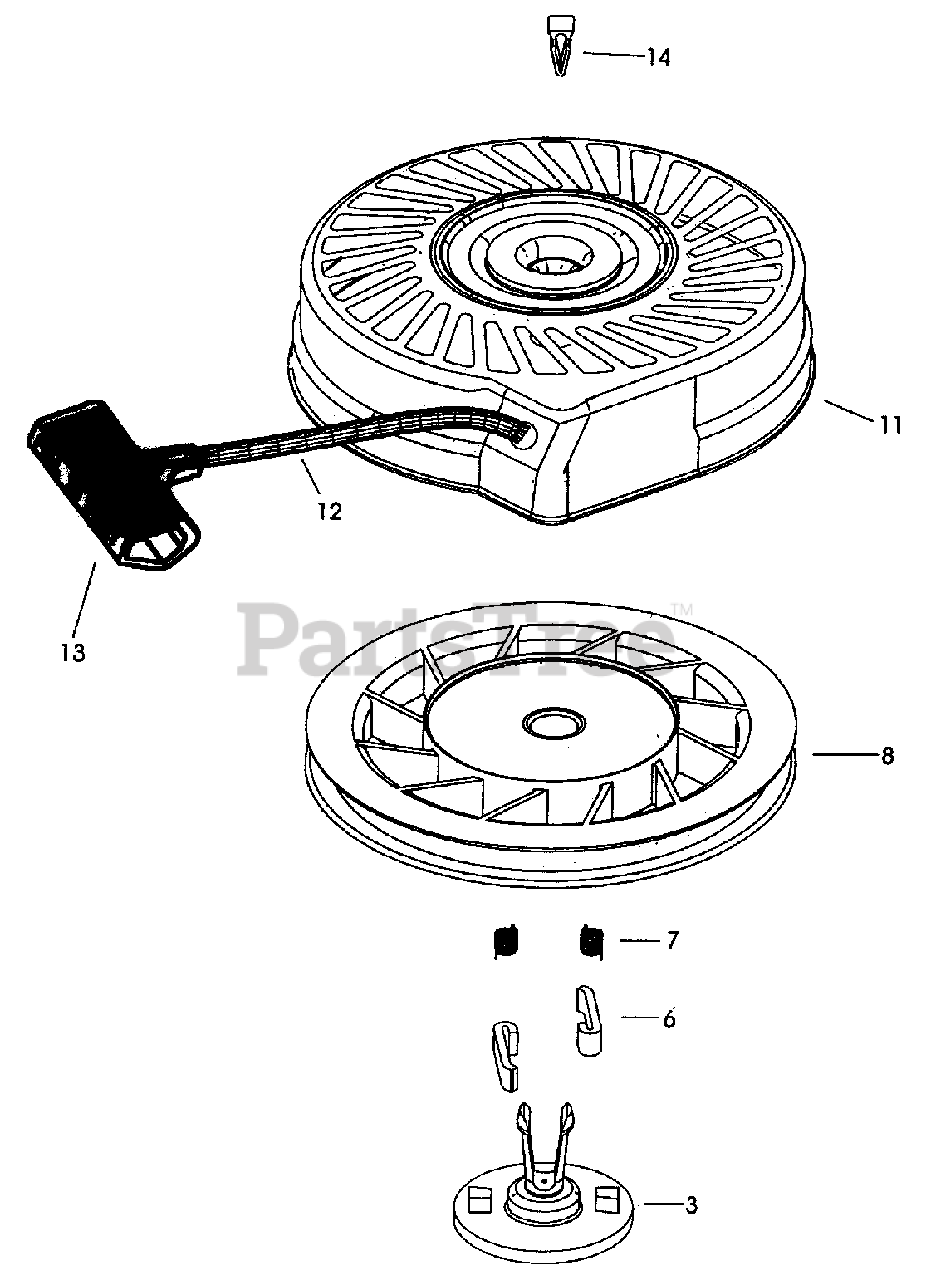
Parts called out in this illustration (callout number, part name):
3	Retainer
6	Starter Dog
7	Dog Spring
8	Pulley & Rewind Spring ASM
11	Starter Housing ASM (40 degree grommet)
12	Starter Rope (Length 98" x 9/64" dia.)
13	Starter Handle
14	Locking Tab
